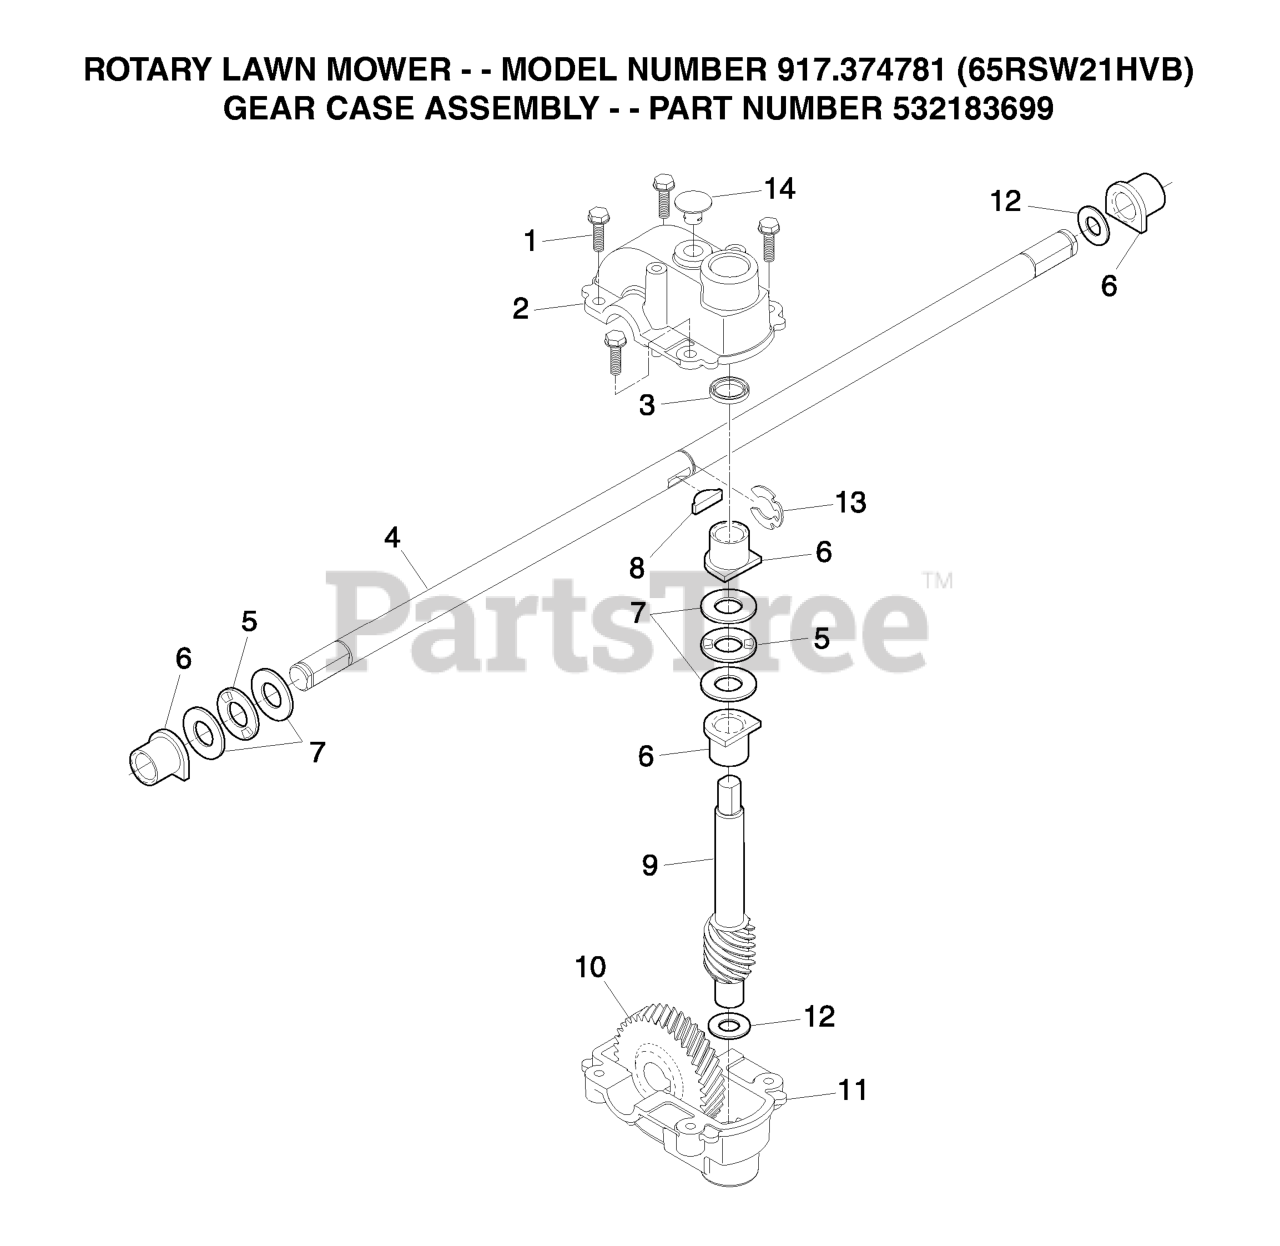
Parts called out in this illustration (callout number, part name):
1	Screw, Hex Washer Head #10-24 x .668
2	GEAR CASE, UPPER
4	SHAFT.DRIVE.HI-VAC.EZ
5	BEARING, NEEDLE, THRUST
7	WASHER, THRUST
8	HI PRO KEY
9	SHAFT.WORM.HI-VAC
10	GEAR, HELICAL
11	GEAR CASE, LOWER
12	THRUST WASHER
14	PLUG.AUGER.GEAR.BOX.SNOW
